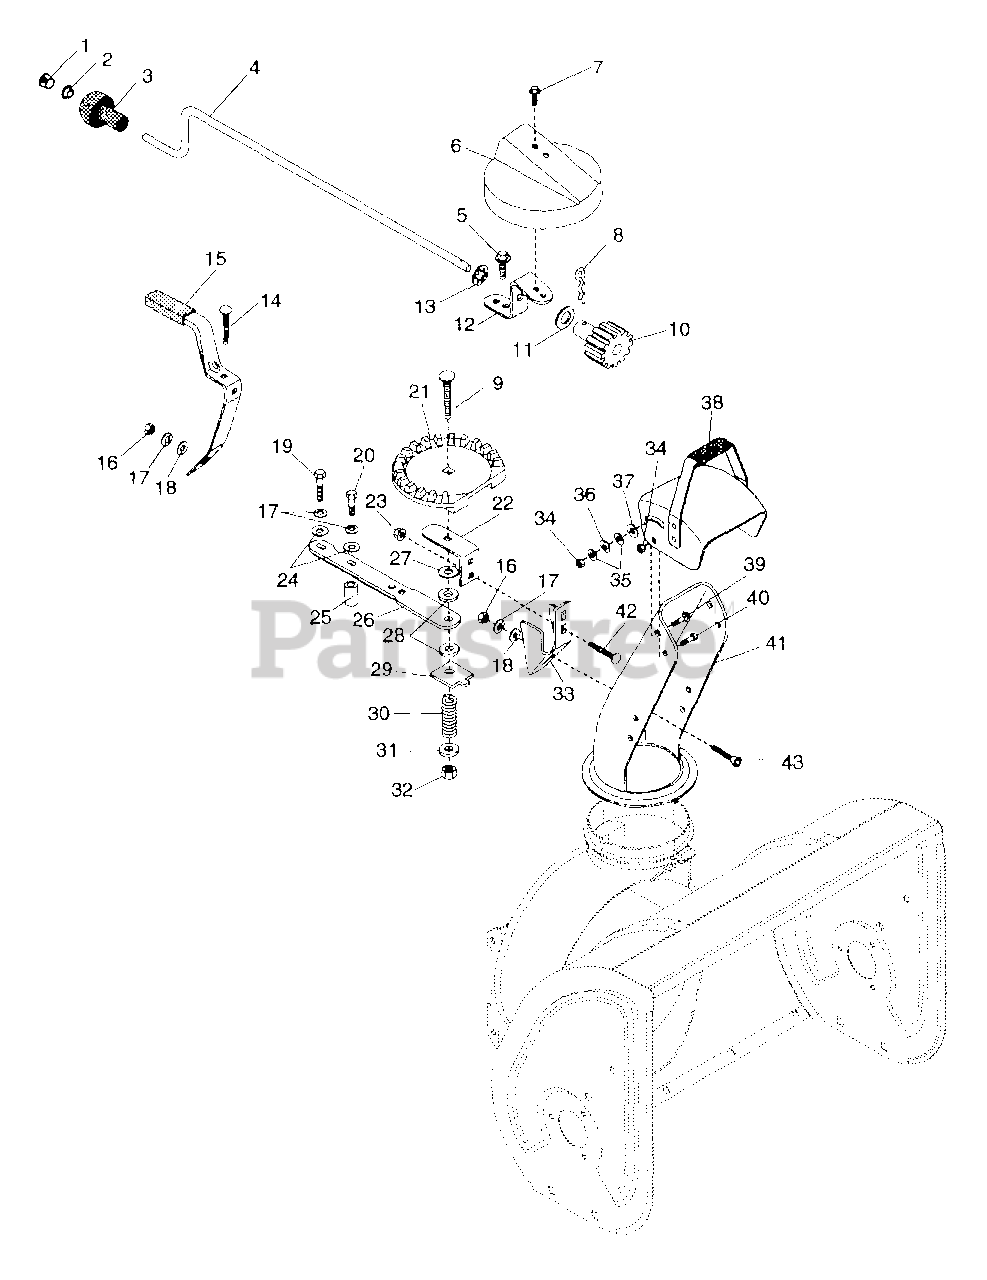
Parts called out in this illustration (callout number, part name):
1	HOLE PLUG
2	RG-RTNG-EXT .375X.010
3	KNOB
4	CHUTE CRANK
5	SCR-TAP .250-20X.50 HXSLHDPL
6	GEAR COVER
7	SCR-TAP .250-20X.37 HWH PL TR
8	PIN-HAIR INT .08X.38X1.42 YWZC
9	BLT-RDHDSQNK .38-16X2.25 SHTPL
10	PINION-CHUTE
11	WSHR-FL-STL .630X1.005X.062 PL
12	BRACKET-GEAR
13	PUSHNUT .625
14	BLT-RDHDSQNK .38-16X2.00 SHTYW
15	CHUTE HANDLE W/PLASTISOL
16	NUT-HEX .250-20 PL
17	WSHR-LK .250X.077 HVY PL
17	WSHR-LK .312X.097 PL HVY
18	WSHR-FL-STL .312X.875X.18 PL
19	BLT-HEX .31-18X.63 PL GR 2
20	BLT-HEX .25-20X1.50 PL GR5
21	CHUTE GEAR
22	GEAR STRAP
23	NUT-LK-FLG .250-20 PL
24	WSHR-FL-STL .328X.875X.062 PL
25	SPACER .280X.625X.760
25	SPACER .280X.625X.640
26	STRAP
26	STRAP-CHUTE CONTROL
27	WSHR-FL-STL .380X1.50X.062 PL
28	FRICTION WASHER
29	FRICTION PLATE
30	SG-COMP .187X.56X1.62
31	WSHR-FL-STL.406X.812X.065PL
32	NUT-LK-CTR .375-16 GR A PL
33	STRAP, CHUTE
34	NUT-LK .312-18 GR A PL
35	WSHR-FL-STL .323X.625X.062 PL
36	WAVE WASHER .390X.655X.110
37	WSHR-PLASTIC .390X.875X.062
38	DEFLECTOR W/DECAL
39	BLT-RDHDSQNK .31-18X.75 SHT PL
40	BLT-HEX .31-18X.50 PL GR2
41	DISCHARGE CHUTE
41	CHUTE-DISCHARGE
42	BLT-RDHDSQNK .25-20X.62 PL
43	SCR-SKH .25-20X.75 FLTCNTRSK
